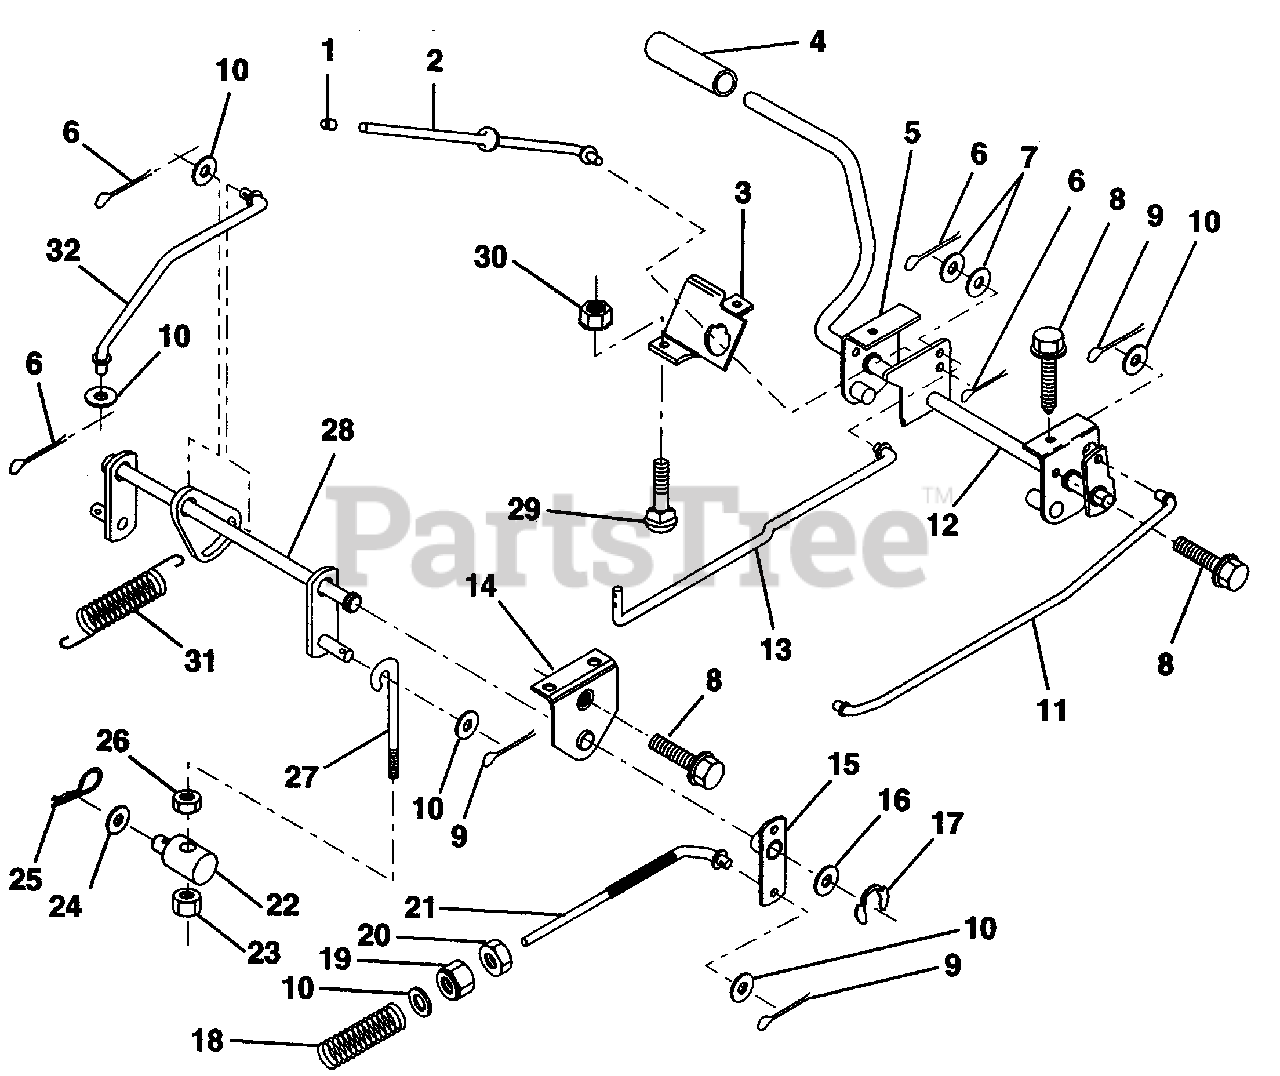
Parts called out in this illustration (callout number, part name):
1	Cap, Plunger (AYP part number)
2	Rod, Parking Brake (AYP part number)
3	Bracket, Parking Brake (AYP part number)
4	Cover, Pedal (AYP part number)
5	Bracket Assy., Clutch Pedal, LH (AYP part number)
6	Pin, Cotter 3/32 x 3/4 (AYP part number)
7	Washer 13/32 x 5/8 x 16 Gauge (AYP part number)
8	Screw, Hex, Thd. Roll. 5/16-18 x 1/2 (AYP part number)
9	Pin, Cotter 1/8 x 3/4 (AYP part number)
10	Washer 13/32 x 13/16 x 16 Gauge (AYP part number)
11	Rod, Front Brake (AYP part number)
12	Assembly, Clutch/Brake Pedal (AYP part number)
13	Rod, Clutch (AYP part number)
14	Bracket, Lift, Shaft (AYP part number)
15	Assembly, Brake, Pivot, Arm (AYP part number)
16	Washer 25/32 x 1-1/8 x 16 Gauge (AYP part number)
17	Ring, Klip (AYP part number)
18	Spring, Brake Rod (AYP part number)
19	Nut, Hex, Jam 3/8-16 UNC (AYP part number)
20	Nut, Crownlock 3/8-16 UNC
21	Rod, Rear Brake
22	Trunnion, Lift (AYP part number)
23	Nut, Crownlock 3/8-16 UNC
24	Washer 13/32 x 1-1/4 x 12 Gauge (AYP part number)
25	Spring, Retainer (AYP part number)
26	Nut, Centerlock 3/8-16 UNC (AYP part number)
27	Link, Threaded (AYP part number)
28	Assembly, Rear Mower Lift (AYP part number)
29	Bolt, Carriage 5/16-18 UNC x 3/4 (AYP part number)
30	Nut, Keps 5/16-18 UNC (AYP part number)
31	Spring, Counterbalance (AYP part number)
32	Link, Lift Lever (AYP part number)
